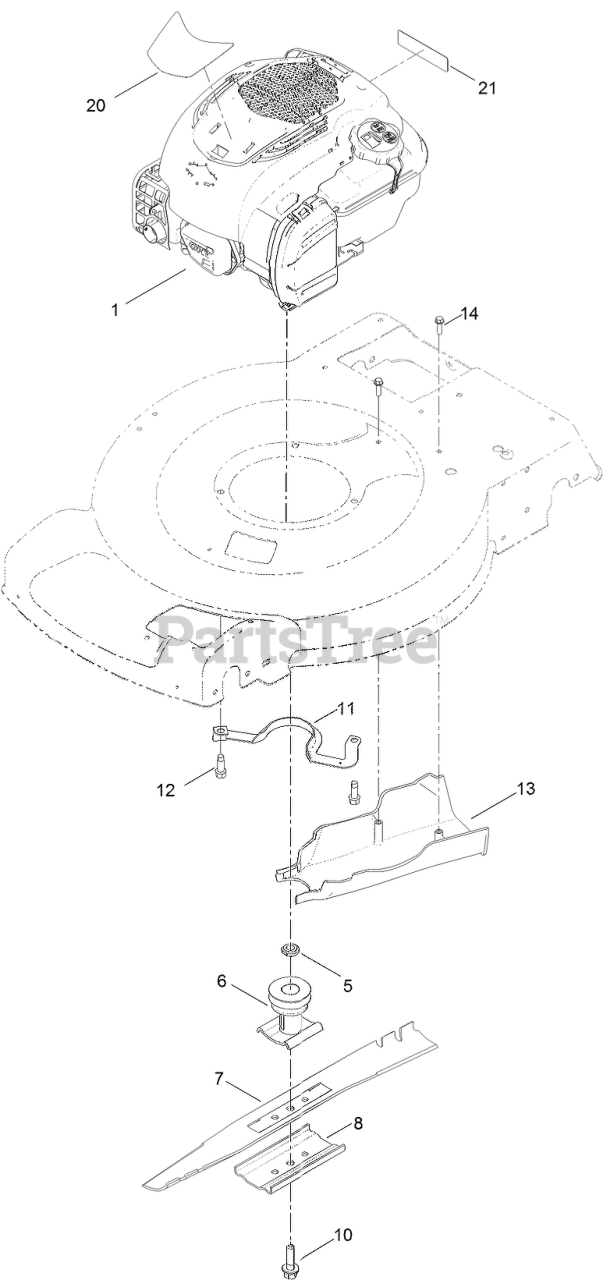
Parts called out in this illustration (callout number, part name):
5	Spacer-Driver
6	DRIVER-BLADE
7	BLADE-22 INCH
8	SUPPORT-BLADE
10	BOLT-BLADE
11	GUIDE-BELT
12	SCREW-TAPTITE
13	COVER-BELT, REAR
14	SCREW-HWH
20	DECAL-SHROUD, BRIGGS
21	DECAL-ARRESTER, SPARK
